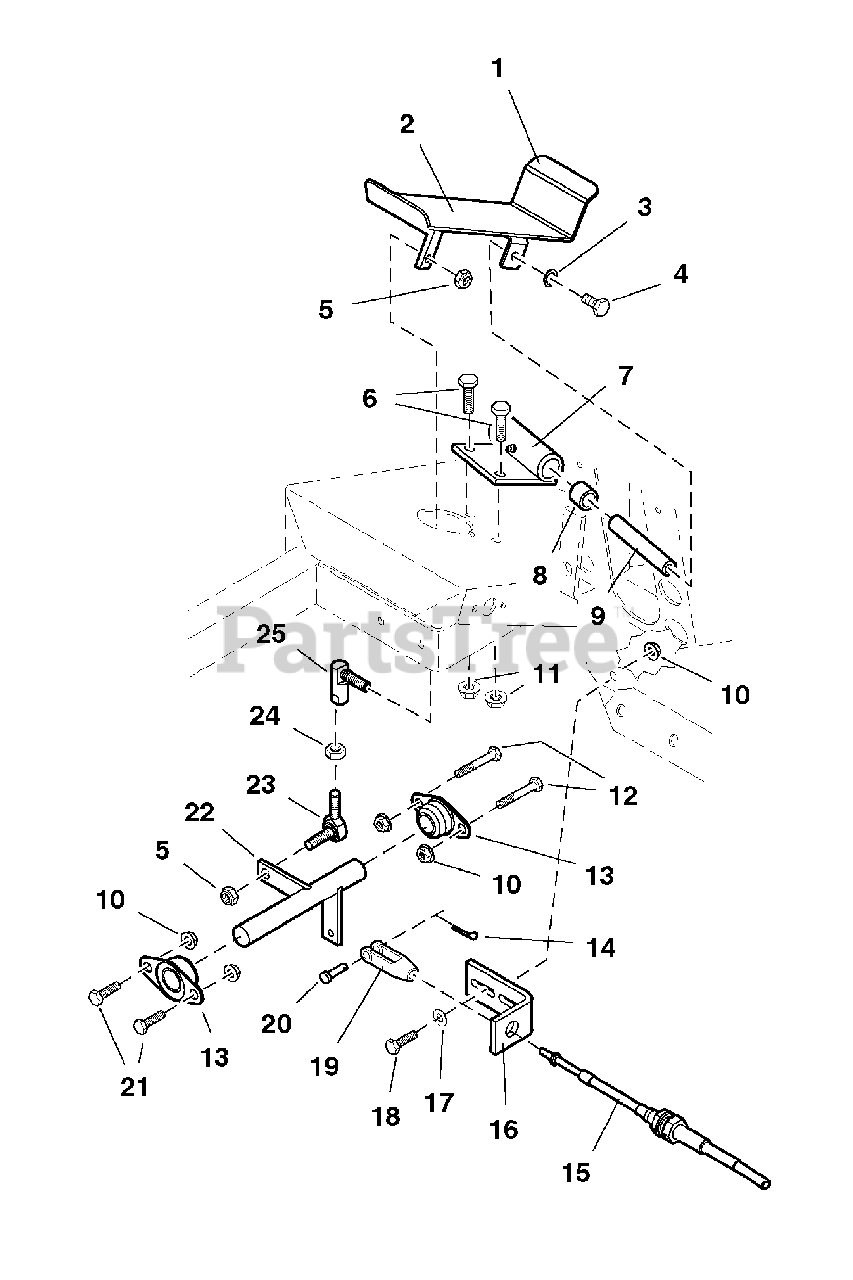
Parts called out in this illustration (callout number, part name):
1	FOOT CONTROL PEDAL
2	SAFETY WALK
3	WASHER, Lock, 3/8
4	CAPSCREW, Hex Hd, 3/8-16 x 3/4
5	NUT, Hex, Nylon Lock, 3/8-24
6	CAPSCREW, Hex Hd, 3/8-16 x 1
7	FOOT PEDAL PIVOT MOUNT, complete (includes ref 8)
8	BUSHING, Plastic
9	PEDAL PIVOT SHAFT
10	NUT, Hex, Serrated Flange, 5/16-18
11	NUT, Hex, Serrated Flange, 3/8-16
12	CAPSCREW, Hex Hd, 5/16-18 x 2-1/2
13	BUSHING, Flange
14	PIN, Cotter
15	SPEED CONTROL CABLE
16	CABLE BRACKET
17	WASHER, 5/16
18	CAPSCREW, Hex Hd, 5/16-18 x 1
19	CLEVIS, Plastic, 1/4-28
20	PIN, Clevis
21	CAPSCREW, Hex Hd, 5/16-18 x 3/4
23	BALL JOINT, 3/8-24 Male, Studded
24	NUT, Hex, 3/8-24
25	BALL JOINT, 3/8-24 Female, Studded
